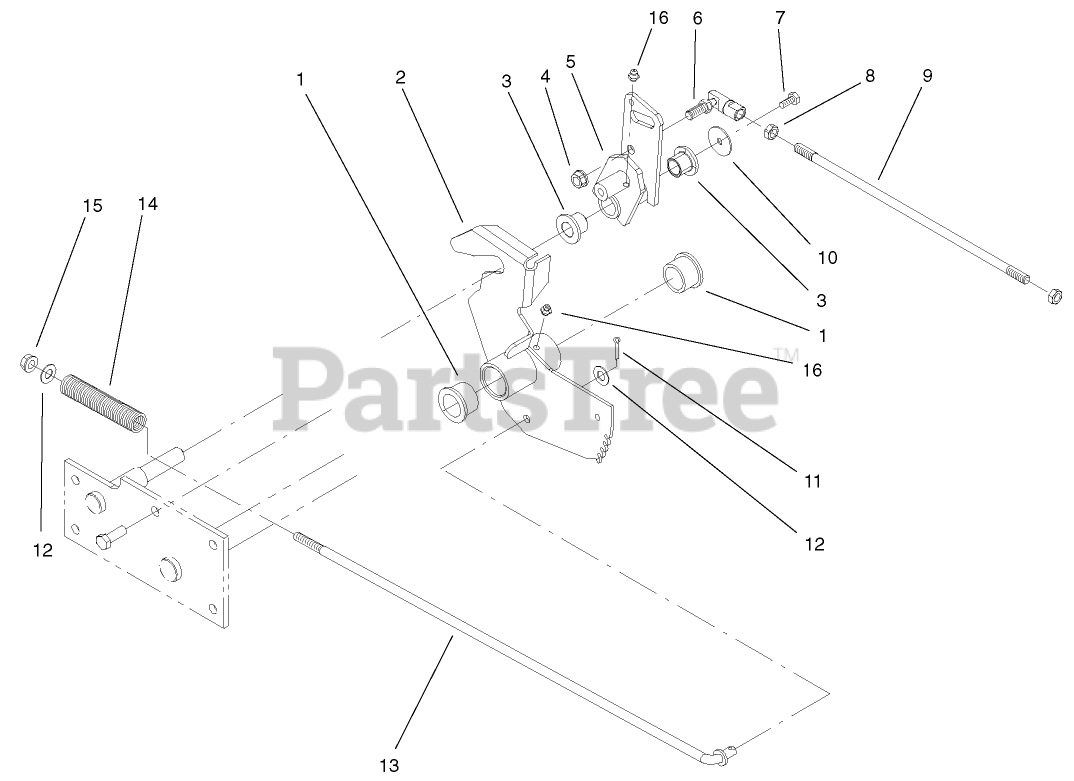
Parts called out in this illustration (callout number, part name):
1	BUSHING-FLANGED
2	PLATE-PIVOT, BRAKE
3	BUSHING
4	NUT-LOCK
5	PIVOT-HYDRO
6	END-TIE ROD, LH
7	SCREW-HH
8	NUT-HEX JAM, LH
9	ROD-PIVOT TO PEDAL
10	WASHER-FLAT
11	PIN-COTTER
12	WASHER-FLAT
13	ROD-BRAKE
14	SPRING-COMPRESSION
15	NUT-LOCK, NI
16	FITTING-GREASE
